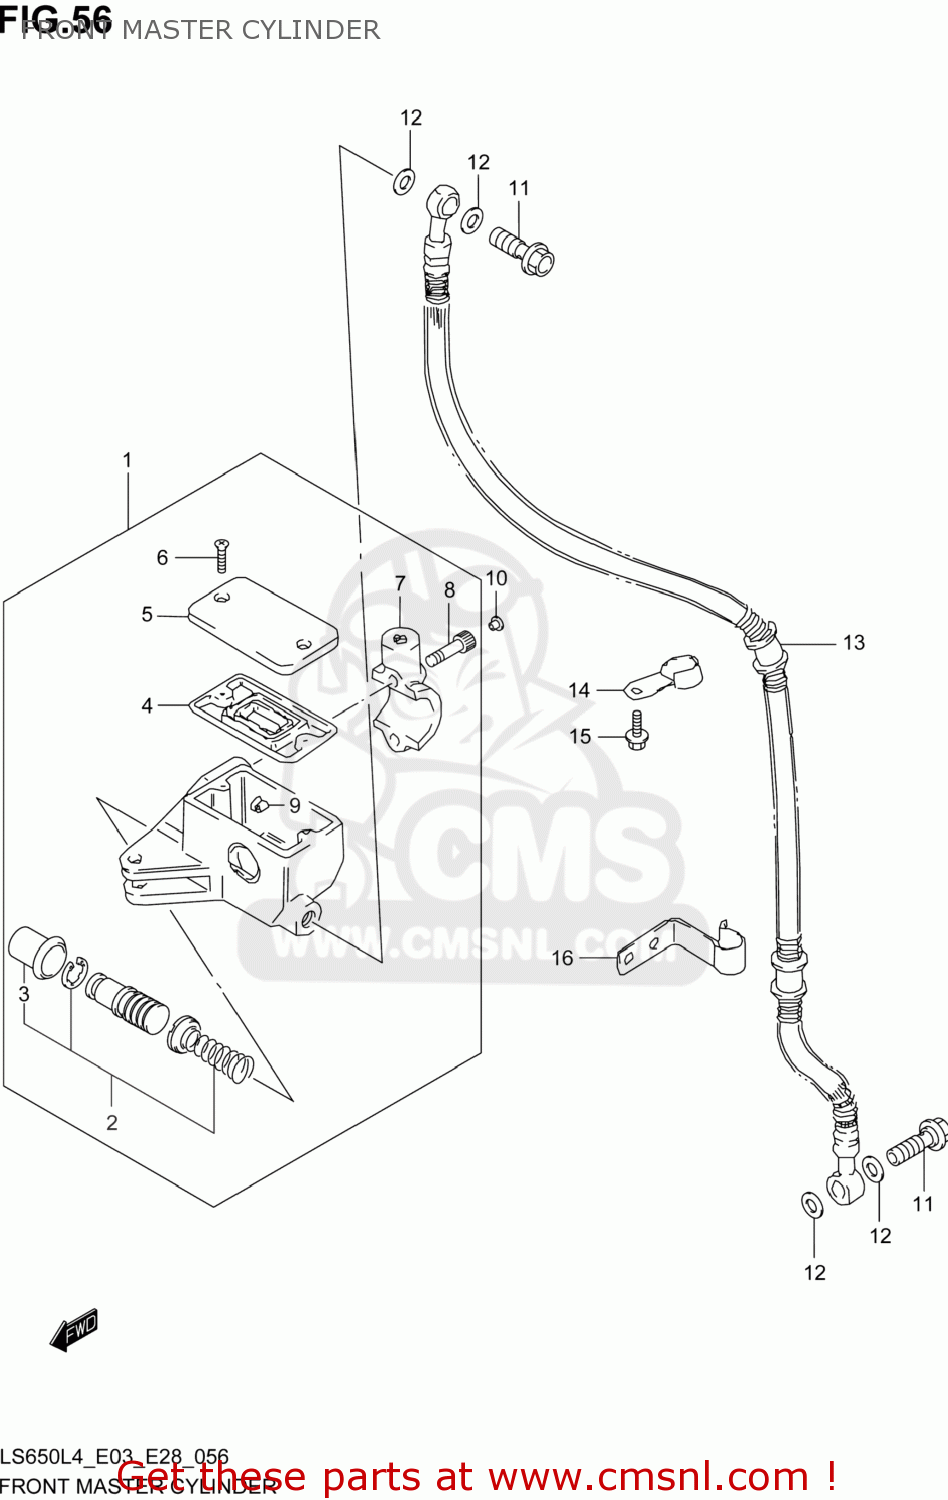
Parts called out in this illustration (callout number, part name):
1	CYLINDER ASSY,FR MASTER
2	PISTON/CUP SET
3	BOOT
4	5
5	CAP
6	SCREW
7	HOLDER
8	BOLT
9	PROTECTOR
10	CAP(OD:10)
11	BOLT UNION
12	WASHER(10X15X1.5)
13	HOSE,FR BRAKE
14	GUIDE,BRAKE HOSE NO.1
15	BOLT
16	GUIDE,BRAKE HOSE NO.2
